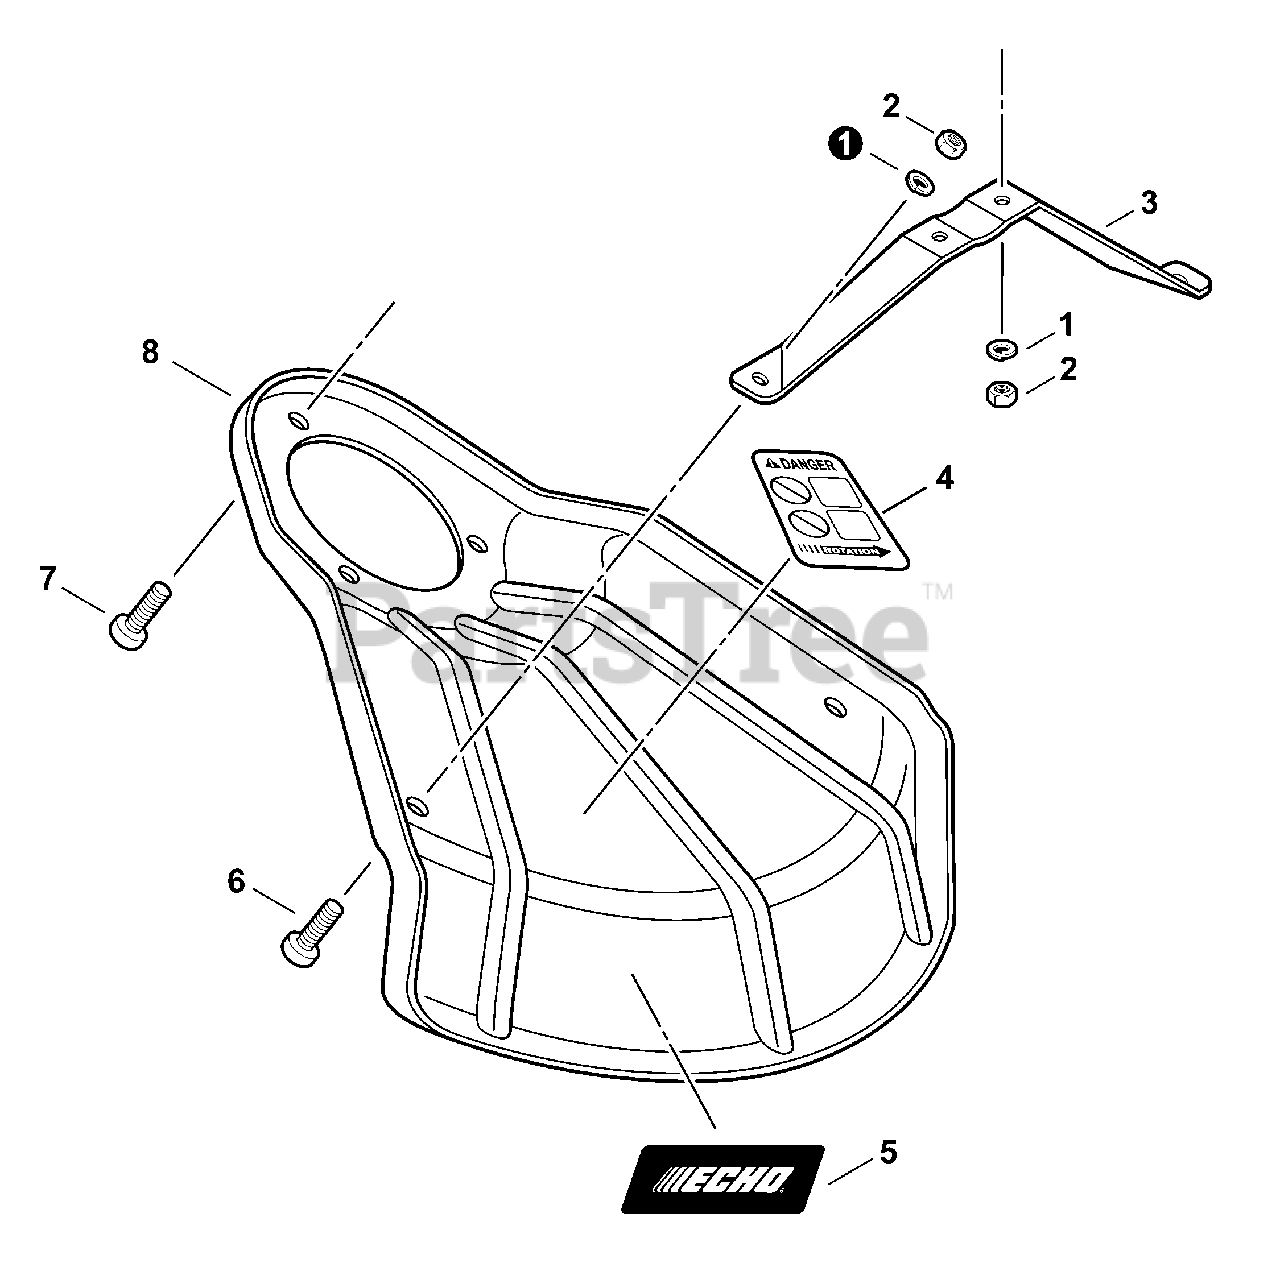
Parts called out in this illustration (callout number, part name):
1	LOCKWASHER
3	BRACKET, SHIELD
4	LABEL - DANGER
5	LABEL - ECHO
6	SCREW - 5×8 -- TORX
7	SCREW - 5×10
8	SHIELD, DEBRIS - METAL
